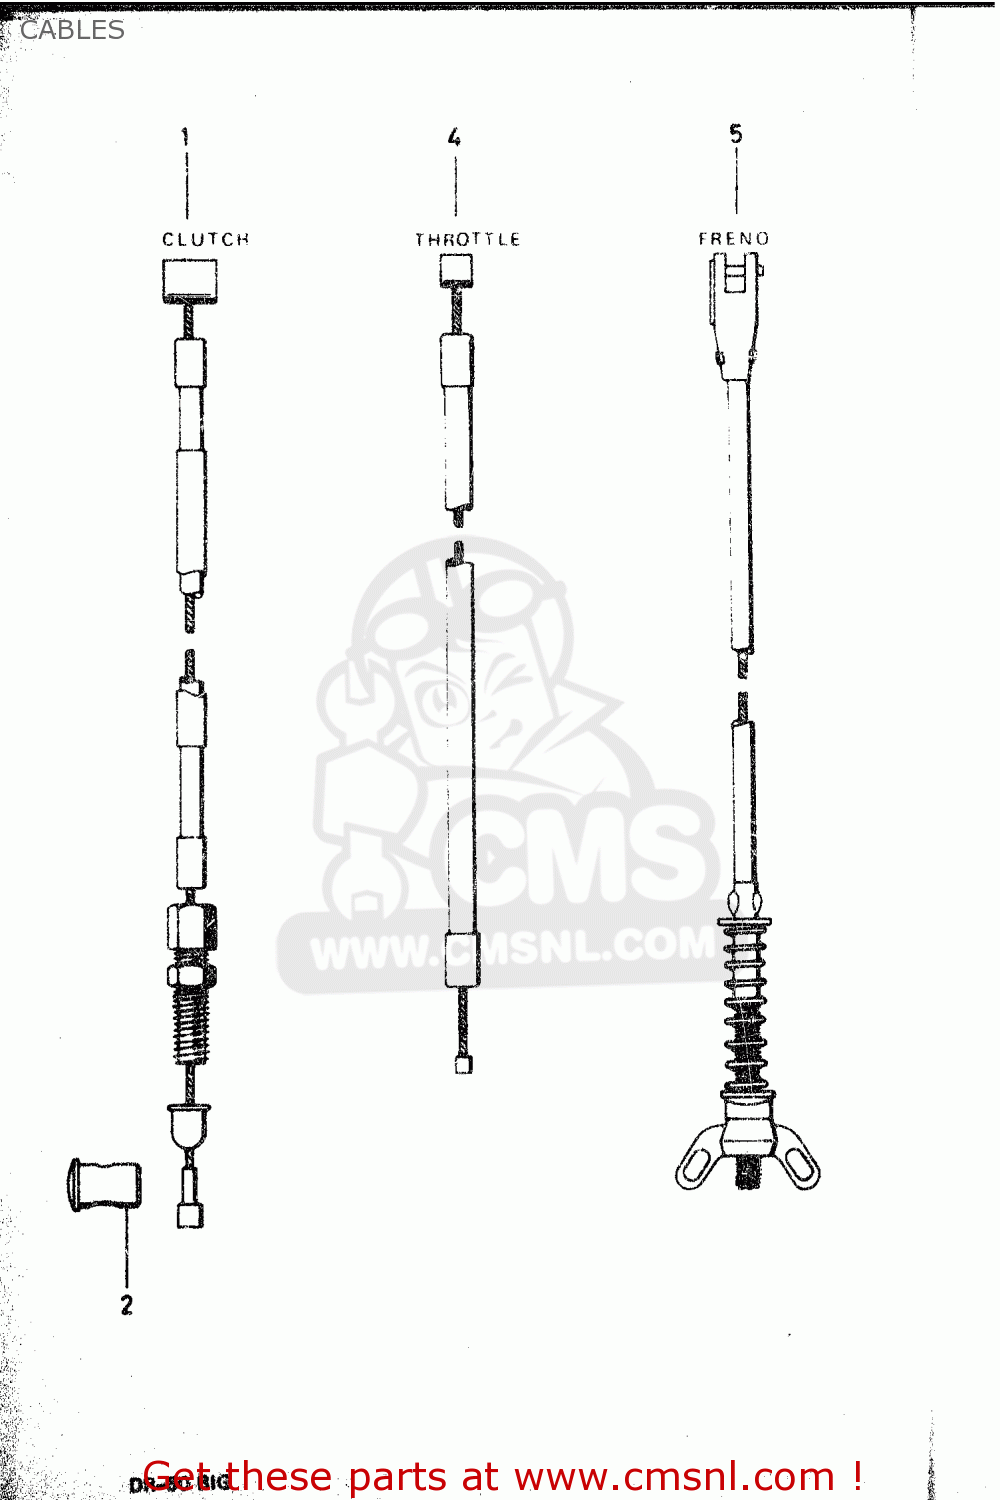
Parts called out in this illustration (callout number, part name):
1	CABLE ASSY, CLUTCH
2	PIN
4	CABLE ASSY, THROTTLE
5	CABLE ASSY, REAR BRAKE
